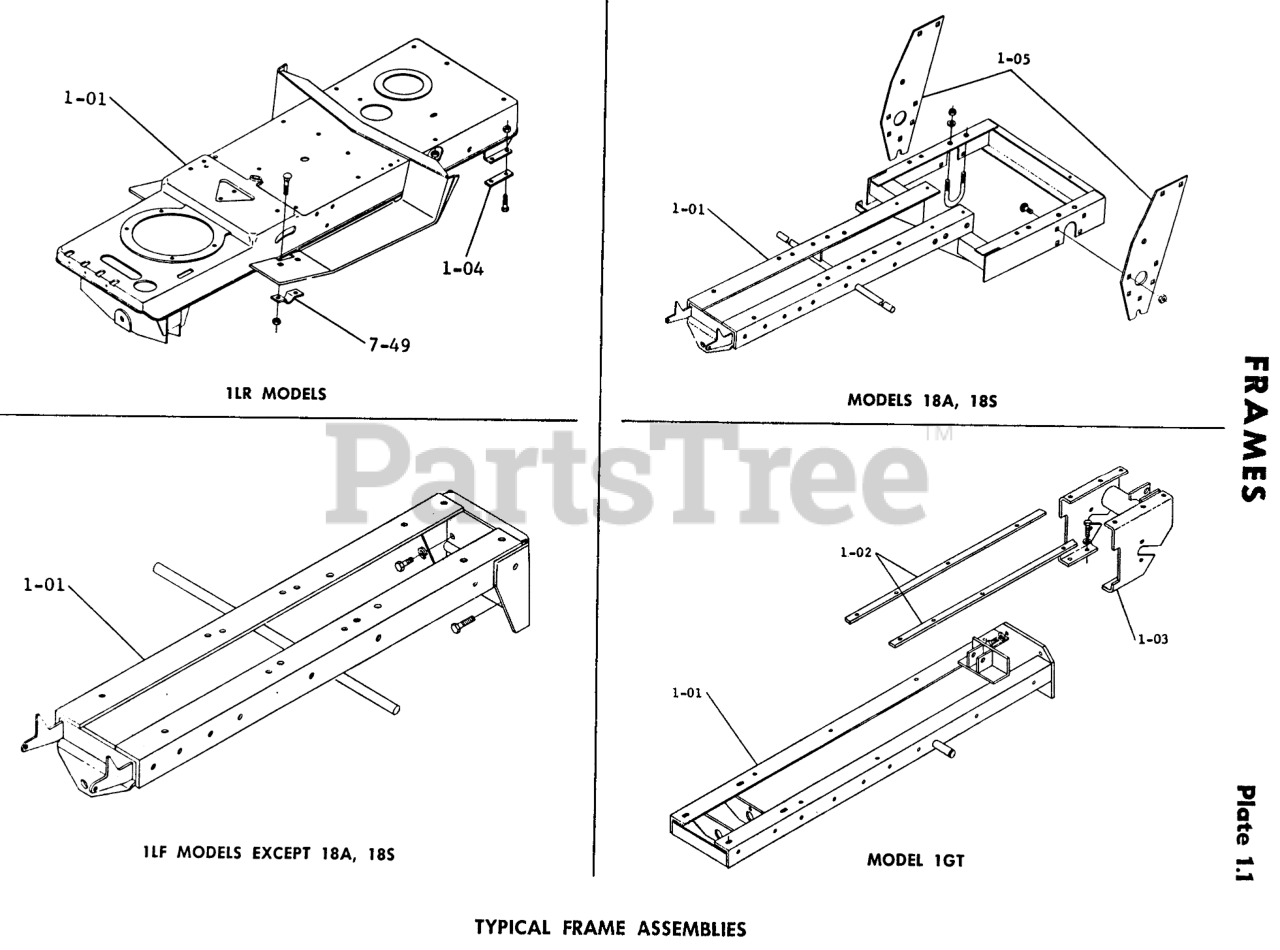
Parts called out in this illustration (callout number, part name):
1-01	Frame
1-01	Bolt 3/8-16 x 3/4 Hex
1-01	Bolt 3/8-16 x 3/4
1-01	Bolt 3/8-16 x 7/8
1-01	Assy.-Frame
1-01	U-Bolt-Trans. mounting
1-01	3/8-16 E.S.
1-01	Washer
1-01	Bolt 3/8-16 x 1
1-01	Lockwasher
1-02	Bar-Frame R.H.
1-02	Bar-Frame L.H.
1-03	Frame Rear
1-03	Bolt 3/8-16 x 7/8
1-03	Lockwasher
1-04	Hanger-Axle
1-04	Bolt Hex 5/6-18 X 2-1/2
1-04	Nut-Nylok
1-05	Plate-Axle Support
1-05	Bolt 3/8-16 x 1
